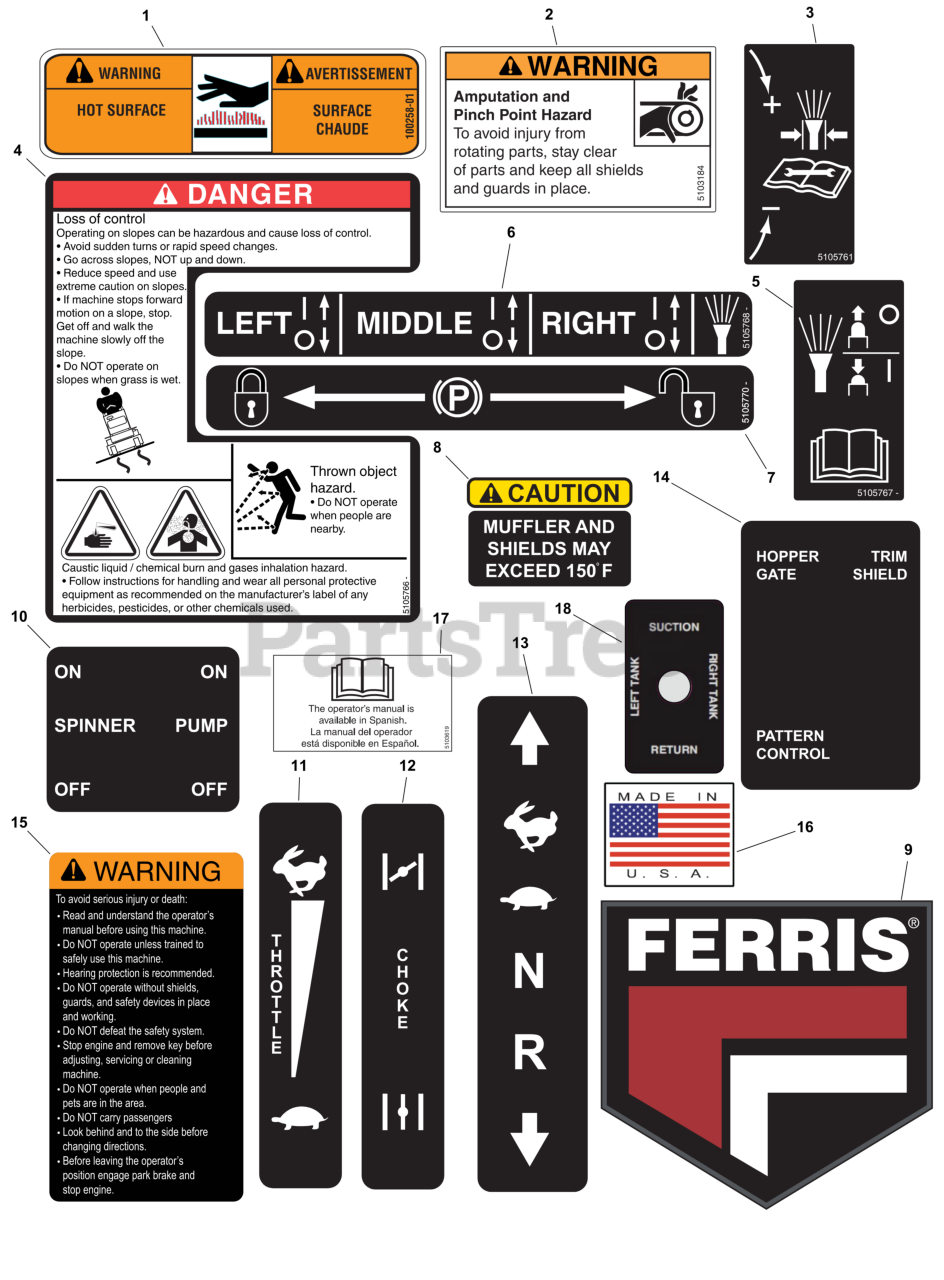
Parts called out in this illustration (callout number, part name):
1	LABEL, CAUTION HOT SURFACE EN/SP
2	DECAL, WARNING, HAND IN BELT, ENG ONLY
3	DECAL, SPRAY PRESSURE CONTROL
4	DECAL, DANGER
5	DECAL, FOOT PLATFORM SPRAY SWITCH
6	DECAL, SPRAY TOGGLE VALVES
7	DECAL, PARKING BRAKE SYMBOLS HORIZONTAL
8	DECAL, CAUTION, MUFFLER TEMP.
9	DECAL, 3.00" FERRIS SHIELD LOGO
10	DECAL, SPINNER PUMP
11	DECAL, THROTTLE
12	DECAL, CHOKE
13	DECAL, MOTION CONTROL
14	DECAL, SPREADER/SPRAYER CONTROLS
15	DECAL, WARNING
16	DECAL, MADE IN THE USA
17	DECAL, MANUAL
18	DECAL, SPRAY TANK SUCTION / RETURN LABEL
